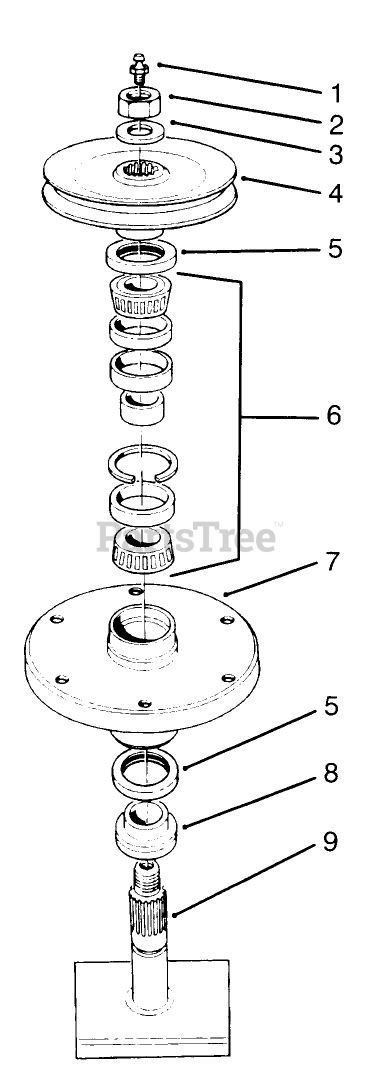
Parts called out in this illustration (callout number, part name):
1	FITTING-GREASE
2	NUT-HEX
3	WASHER
4	PULLEY & HUB WA
5	SEAL-OIL
6	BEARING ASM
7	Housing-Spindle
8	SPACER
9	SHAFT
